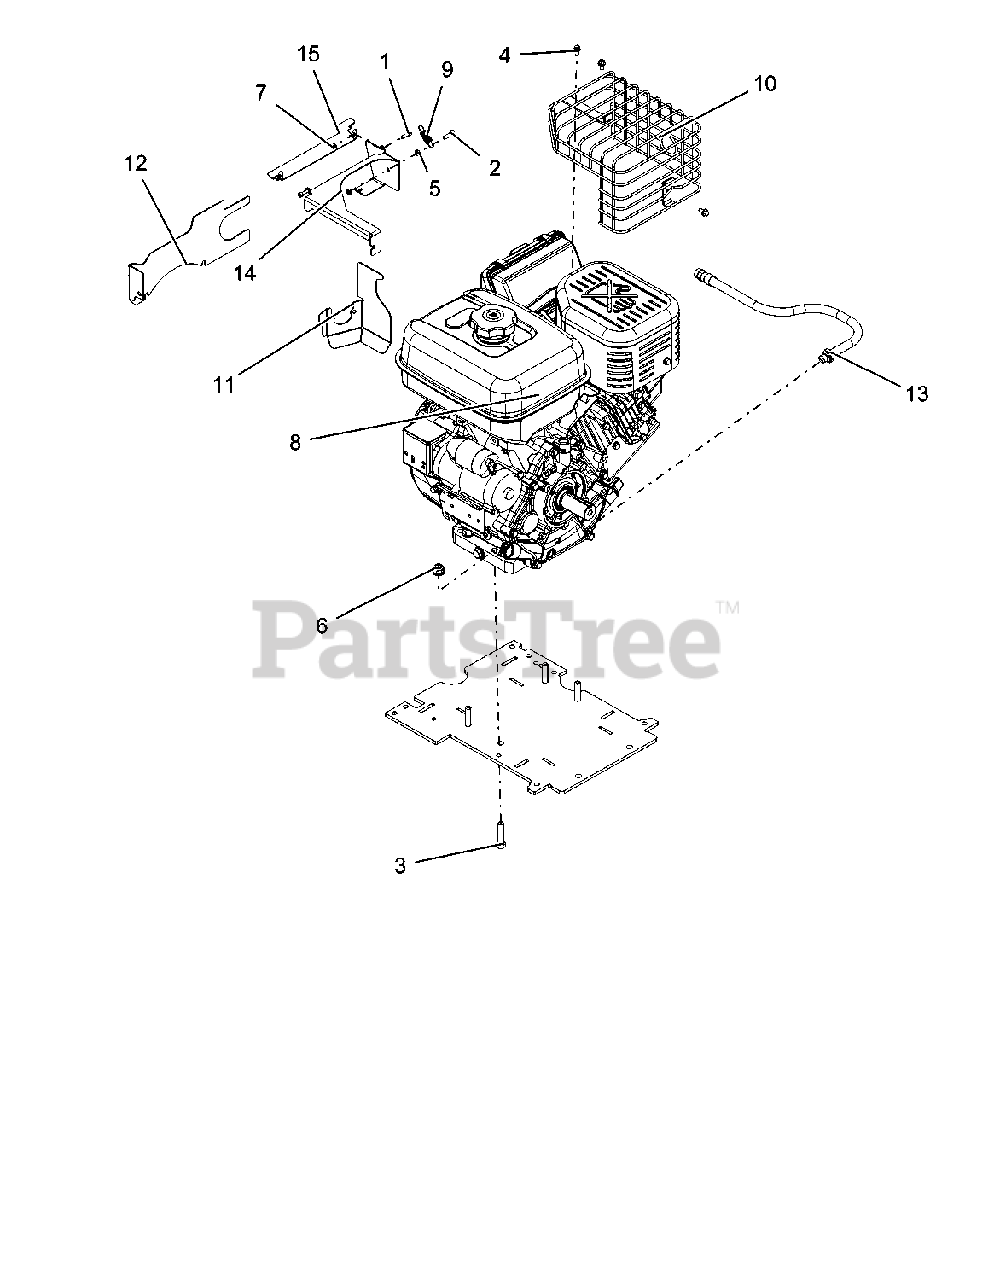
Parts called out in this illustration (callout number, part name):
1	SCR, SKH M5-.8 X 16 GR12.9 ROHS
2	BLT, HEX M6-1X20 GR8.8 ZC120
3	BLT, HEX M10-1.5X45 GR8.8 ZC120
4	BLT, HEX M6-1X12 GR8.8 ZC120
5	NUT, HEX-JAM M6-1.0 GR8.8 ZC120
6	NUT, LK-NYL-FLG M10-1.5 GR8.8 ZC120
7	NUT, LK-NYL M5-0.8 GR8.8 ZC120
8	ENGINE, SUBARU EX40 - 12V
9	SG-TENS .041X.500X1.750
10	HEAT SHIELD
11	PLATE, WINTERIZE CARB (BLACK)
12	PLATE, WINTERIZE RECOIL (BLACK)
13	ASM, HOSE OIL DRAIN W/CAP
14	PLATE, ENGINE COVER-BLACK
15	PLATE, ENGINE FLAP-BLACK
